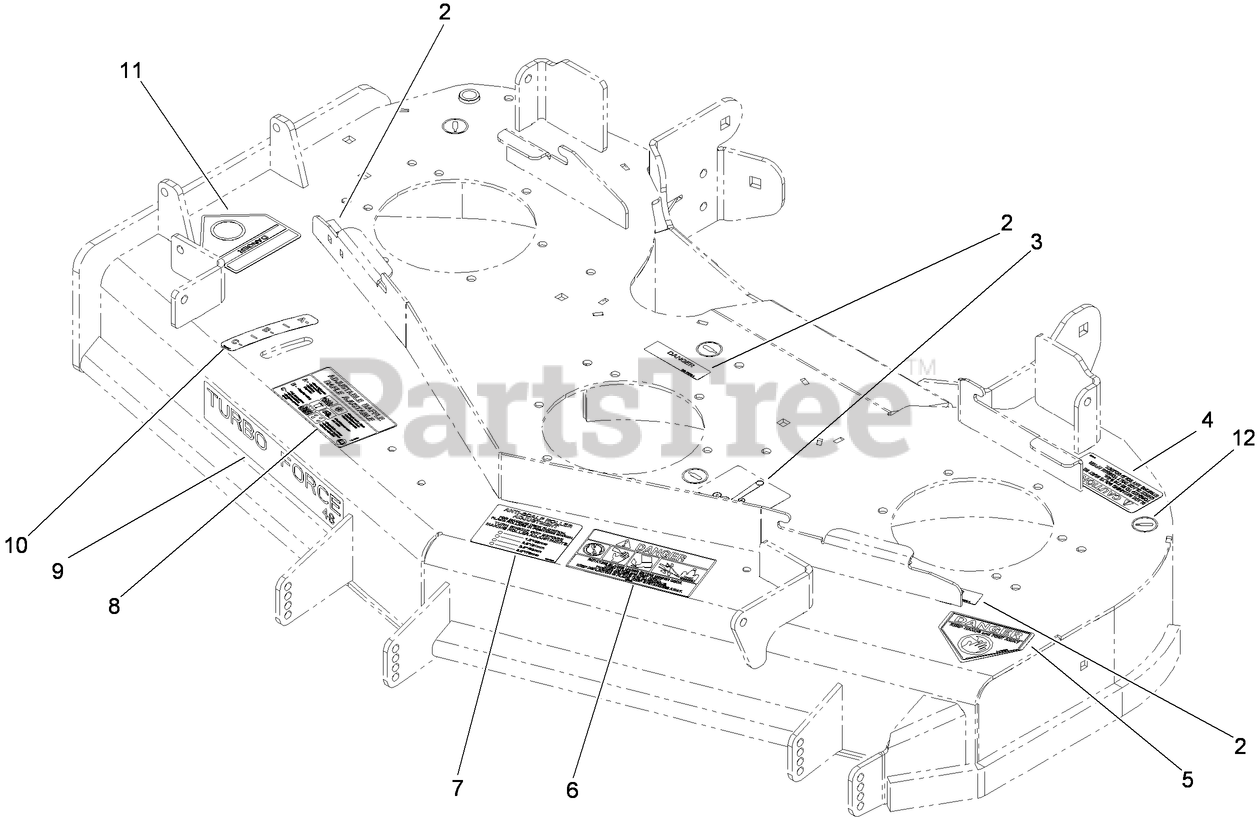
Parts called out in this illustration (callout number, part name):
2	DECAL-COVER, MISSING
3	DECAL-ROUTING, DECK BELT
4	DECAL-TORQUE
5	DECAL-DANGER
6	DECAL-DANGER, THROWN OBJECT
7	DECAL-SCALP, ANTI
8	DECAL-ADJUSTMENT, BAFFLE
10	DECAL-SETTING, BAFFLE
11	DECAL-DANGER
12	DECAL-GREASE
